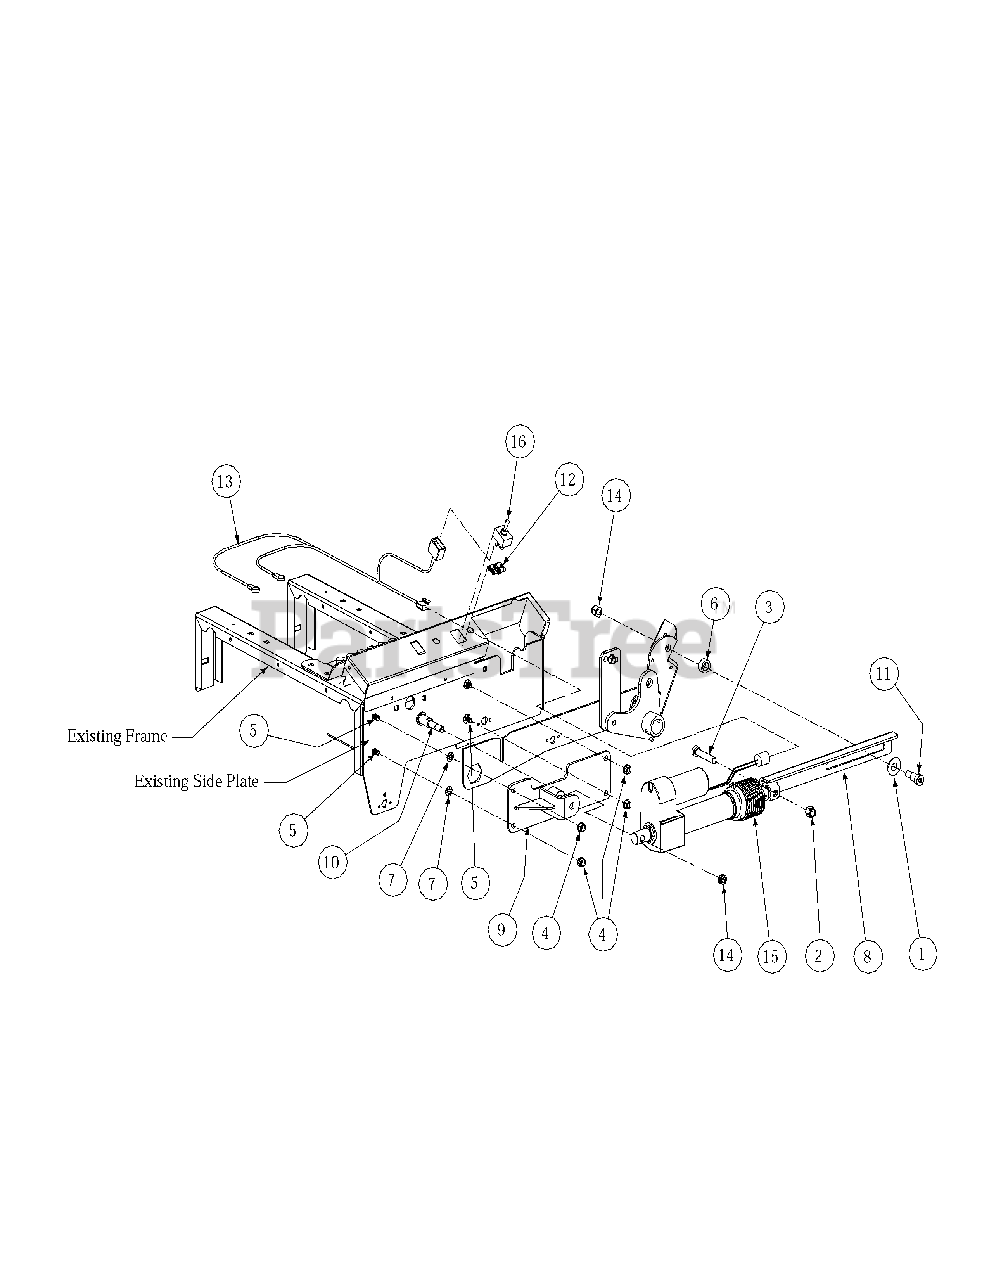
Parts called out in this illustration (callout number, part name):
1	Washer, 1-1/2 x 5/8 x .05
2	Nut, 1/2-13, Nylon Insert
3	Hex Head Cap Screw, 1/2-13 x 2-1/2
4	Nut, 3/8-16, Hex Flange Lock
5	Carriage Bolt, 3/8-16 x 1
6	Spacer, .630 ID x 1.06 OD x .440
7	Push Retainer, 3/8
8	Arm Lift Deck Weldment
9	Actuator Mounting Plate
10	Pin, Deck Pivot Lift
11	Shoulder Screw, 0.625 x .750
12	Label, Deck Lift Up/Down
13	Harness Assembly
14	Jam Nut, 1/2-13
15	Actuator
16	Toggle Switch, On-Off-On
